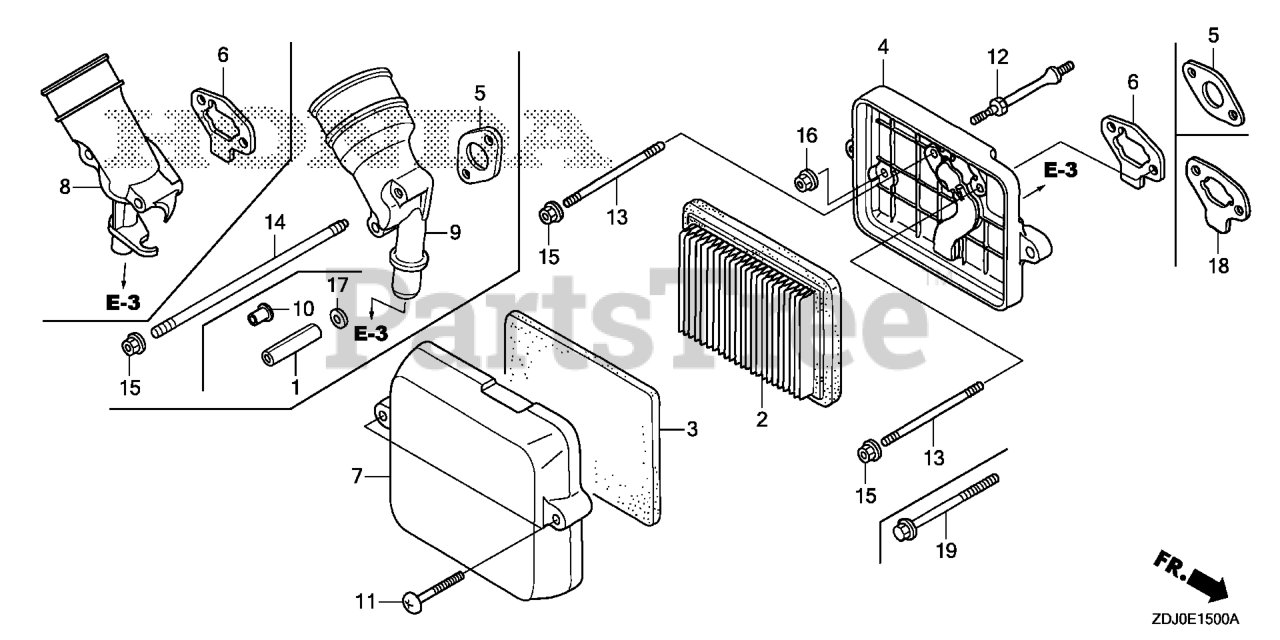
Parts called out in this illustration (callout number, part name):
2	ELEMENT, AIR CLEANER (TOYO ROKI) (ENGINE NO.)
3	FILTER (OUTER)
4	HOUSING, AIR CLEANER
7	COVER, AIR CLEANER
11	BOLT, AIR CLEANER COVER
12	BOLT, STUD
16	NUT, FLANGE (6MM)
18	GASKET, AIR IN. JOINT
19	BOLT, FLANGE (5X77) (CT200)
